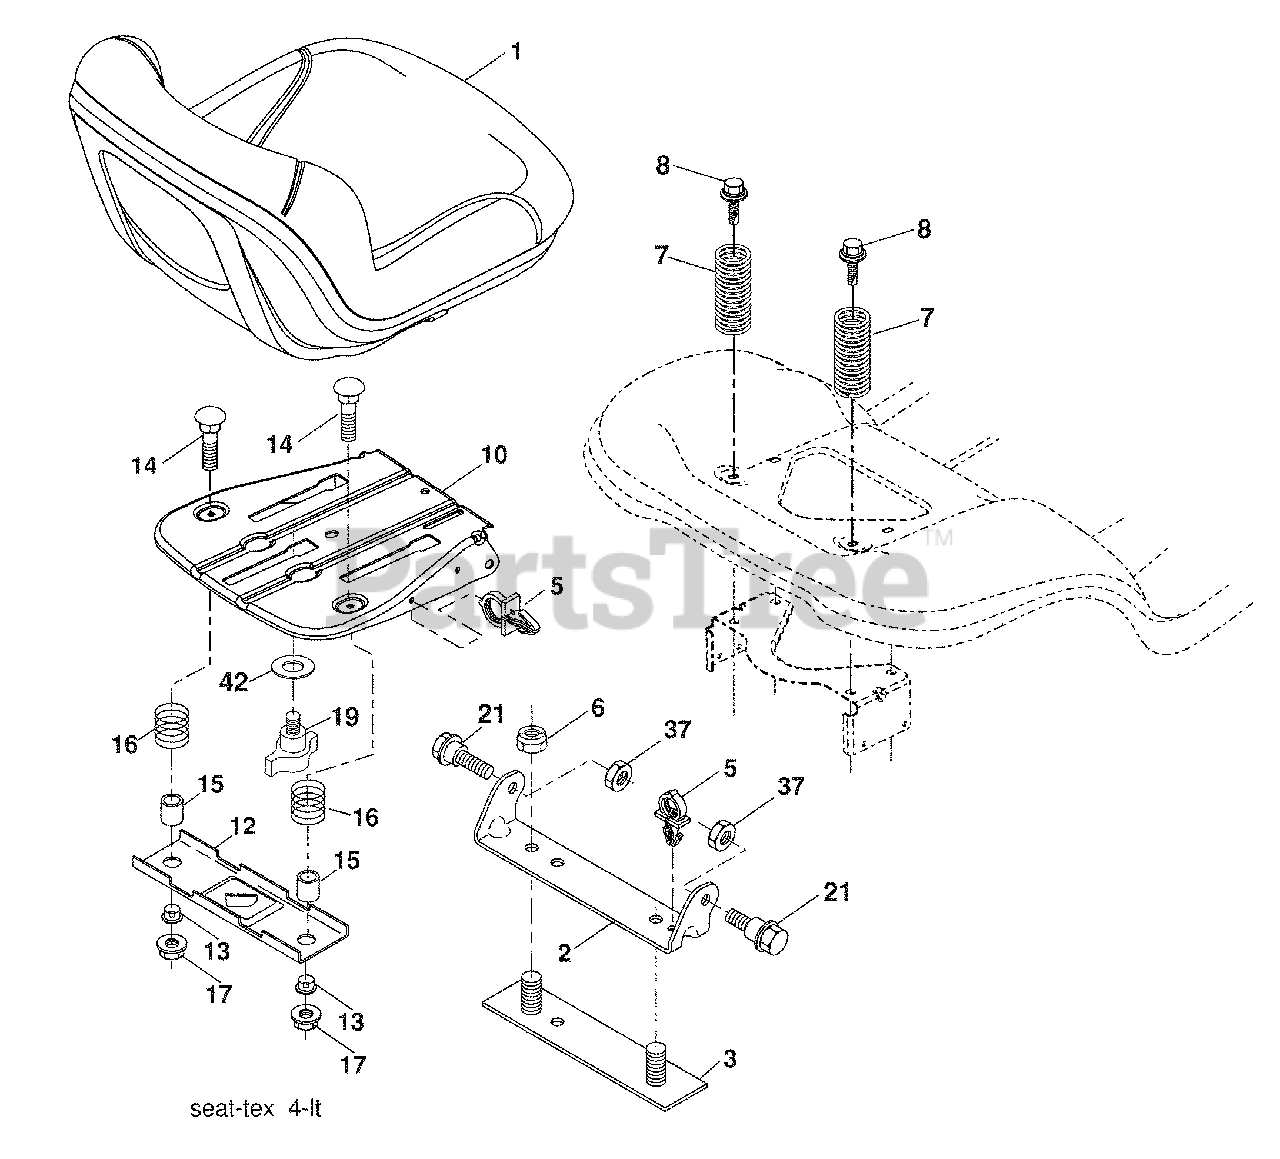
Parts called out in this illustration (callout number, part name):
1	Seat
2	Bracket Pivot Fender
3	Strap, Asm Fender
5	Clip, Push In, Hinged
6	Nut, Lock W/Ins. 3/8-16 unc
7	Spring, Seat Cprsn
8	Bolt 5/16-18 uncx 3/4 w/Sems
10	Pan, Seat
12	Bracket Mnt Seat
13	Bushing Snap
14	Bolt 1/4-20 x 1/2
15	Spacer Split
17	Nut Lock 1/4
21	Bolt, Shoulder 5/16-18
37	Nut, Lock 5/16-18 unc
42	Washer Cup Seat
